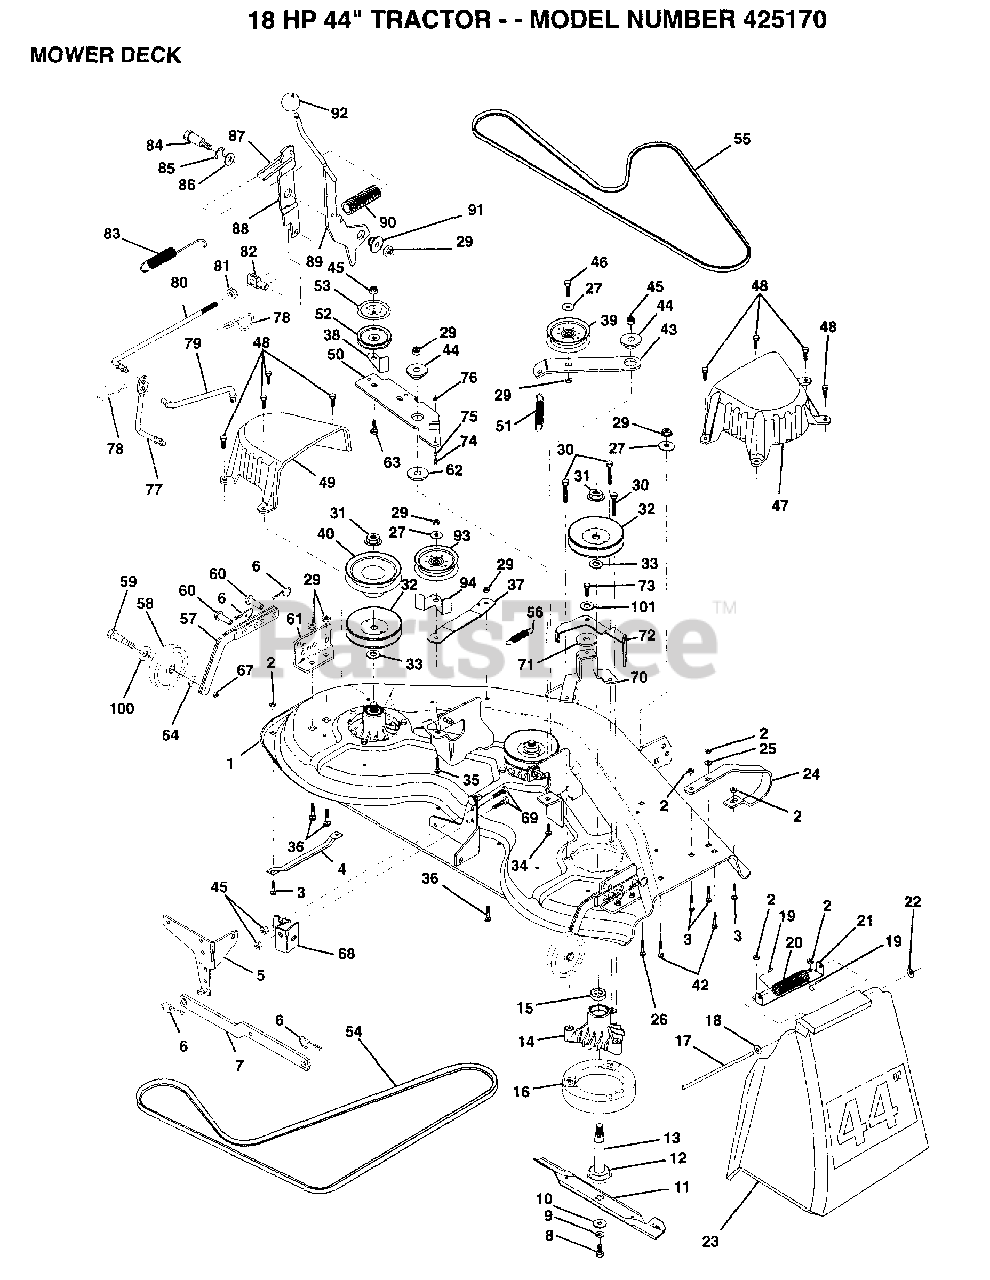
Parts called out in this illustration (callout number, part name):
1	"DECK ASM WELD44"""
2	NUT
4	RUNNER-LH M
5	BRKT.ASM.SW.44/50
8	BLADE BOLT
10	WASHER.HARD.BLADE
11	"BLADE.44"" HIPERF"
12	BEARING.BALL
13	SHAFT.ASM.W/BRNG
14	HOUSING.MAND.44.V
15	BEARING
17	ROD-HINGE T
18	WASHER
19	CAP-SLEEVE LT
20	SPRING TORSION
21	BRKT DEFLECTOR
22	NUT PUSH M
23	DEFLECTOR SHIELD
24	RUNNER.RH
25	WASHER M
26	BOLT
27	WASHER
29	NUT
33	WASHER
34	BOLT.3/8-14X1.25
35	BOLT
36	BOLT D
37	STIFFENER.ARM.IDL
38	KEEPER BELT IDLER
39	FLAT IDLER PULLEY
40	"PULLEY.DRIVEN.44"""
42	BOLT
43	"ARM.IDLER.SEC.44"""
44	SPACER RETAINER
47	"COVER.MAND.RH.44"""
48	SCREW.1/4-20X5/8
49	COVER.MANDREL.LH
50	ARM.IDLER.PRIMARY
51	"SPRING.SEC.44""VEN"
52	PULLEY.IDLER.VGRO
53	SHIELD.IDLER.44.V
54	BELT-V MOWER PRIM
55	BELT-V.88.12.MW
56	"SPRING,EXTENTION"
57	BAR.ASM.GUAGE.WHL
58	WHEEL.GAGE.BLK.PL
59	BOLT M
60	PIN.CLEVIS
61	BRACKET.GUAGE.WHL
62	HARDENED WASHER
63	BOLT.3/8-16X1.50
64	WASHER
67	NUT
68	BRACKET PVT MCH
70	"BRACKET SUPT 44"""
71	HARD SMALL WASHER
72	ARM BRAKE ASM
73	BOLT.SHLD.5/16-18
75	SHOULDER BOLT
76	LOCKNUT
77	PIVOT ROD
78	RETAINER M
79	ROD CLUTCH SECON
80	ROD.CLUTCH.PRIM44
81	NUT
82	TRUNION ADJ
83	RETURN SPRING
84	SHOULDER BOLT
85	RING
86	WASHER
87	SPRING KEEPER
88	CLUTCH ARM SECOND
89	LEVER.CLU.PRIM.
91	BUSHING
93	IDLER-FLAT T
100	WASHER
101	HARD SMALL WASHER
